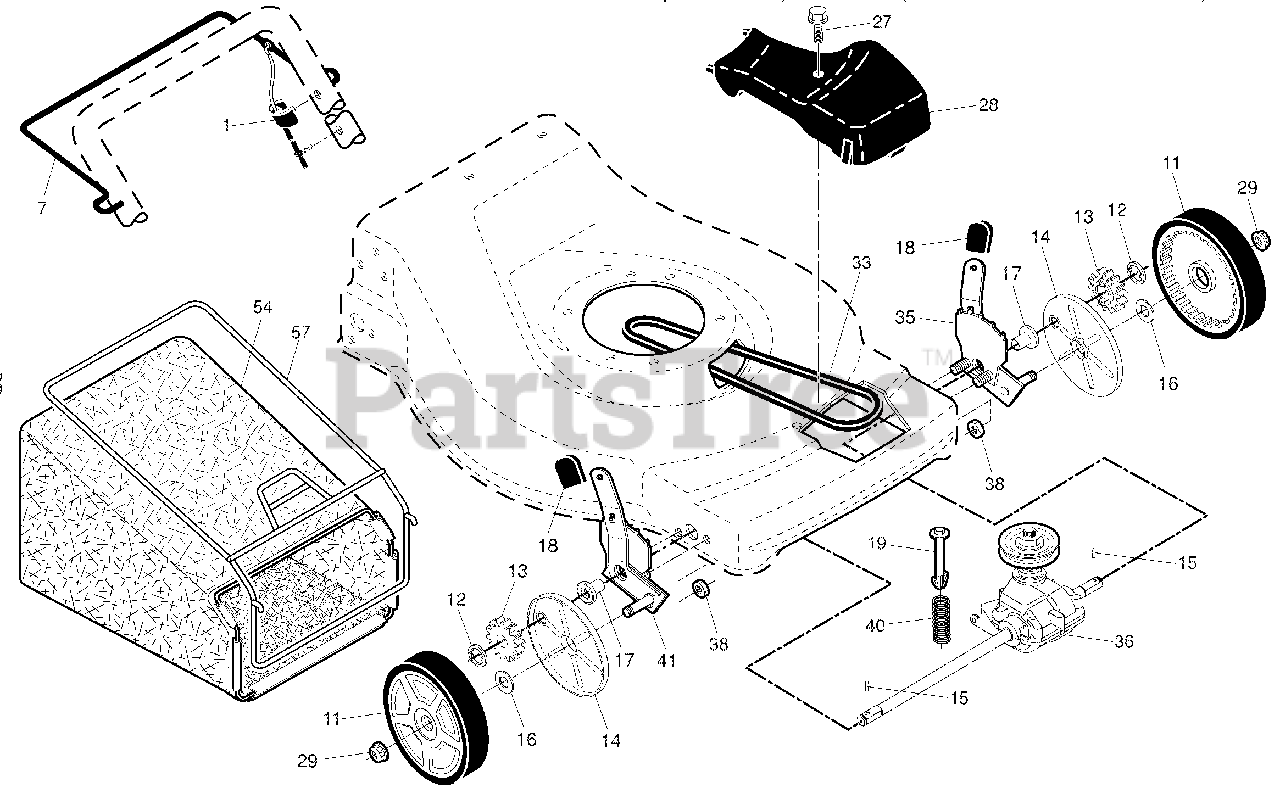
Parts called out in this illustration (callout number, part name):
1	CABLE, DRIVE CONTROL
7	Control Bar, Drive
11	WHEEL AND TIRE ASSEMBLY-FRONT
14	Dust Cover
15	Pawl, Drive
16	Washer, Flat 3/8
17	BEARING
18	Selector Knob
19	Retainer, Spring
27	Pan Head Tapping Screw #10-24
28	DRIVE COVER
29	Nut, Hex
33	DRIVE BELT
35	KIT,WHEEL ADJUSTER, RH (INCLUD
36	Gear Case Assembly, Complete
38	Locknut, Hex 1/4-20
41	KIT,WHEEL ADJUSTER, RH (INCLUD
57	BAG FRAME
